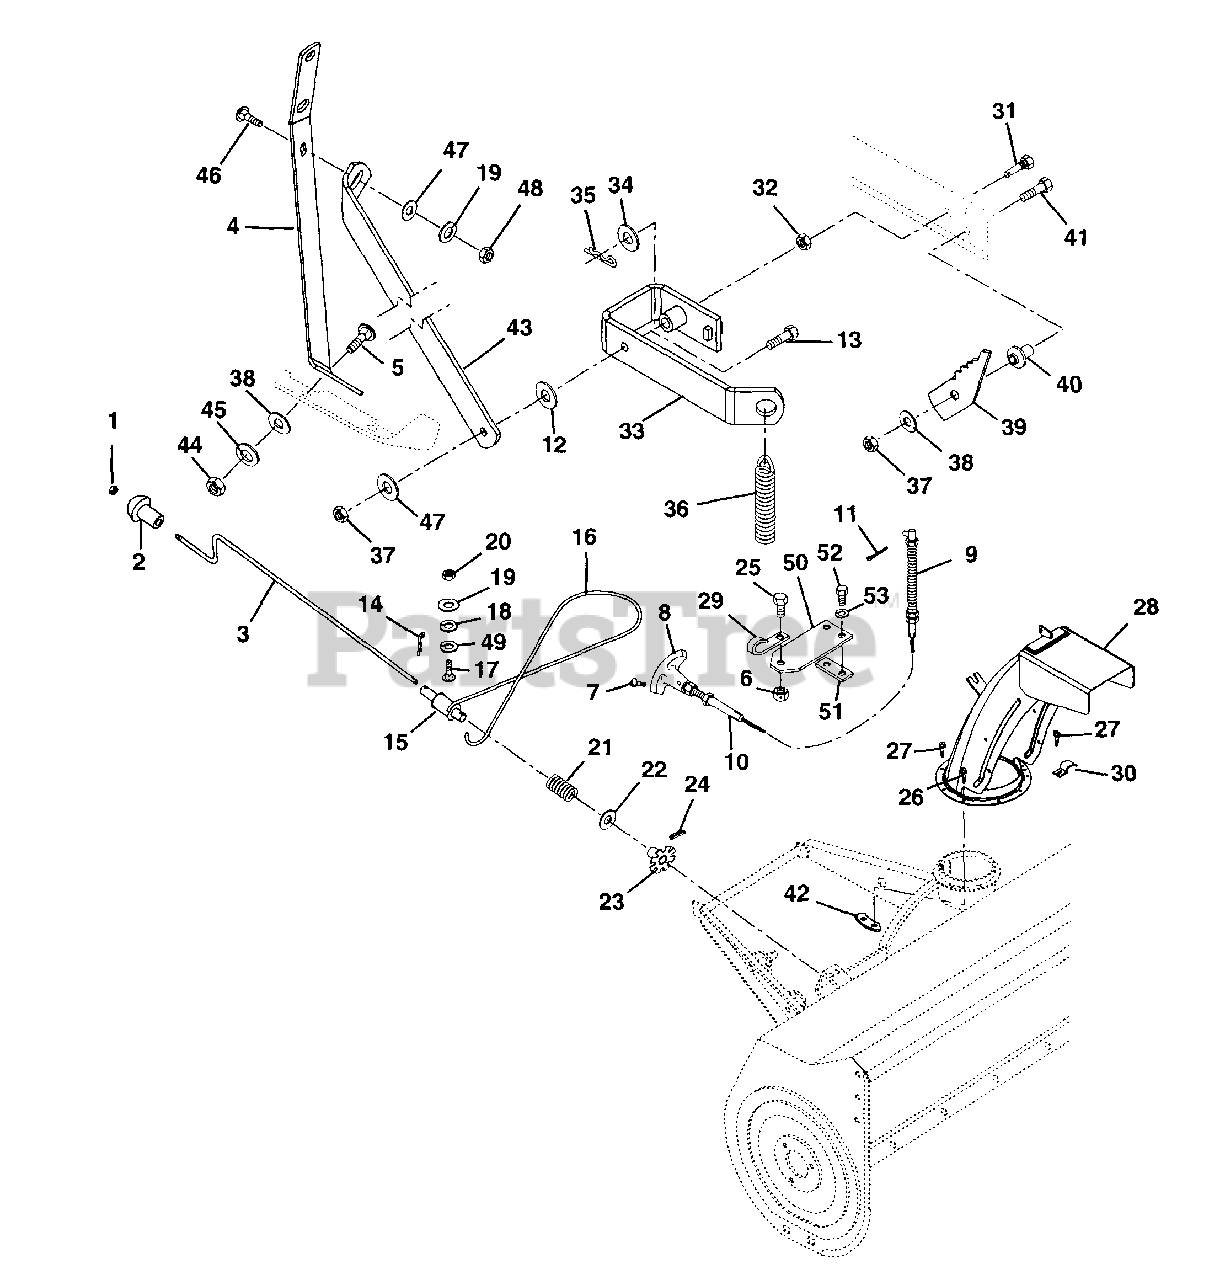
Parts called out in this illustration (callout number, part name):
1	@NUT-LK-CTR-JAM .375-16 YWZC
3	CHUTE CONTROL CRANK
4	SUPPORT, ROD
5	@BLT-RDHDSQNK .38-16X1.00 G5YZ
6	@NUT-LK-CTR .38-16 YWZC
7	@SCR-MCH 8-32X.75 HWH YWZC
8	KNOB, CONTROL
10	CABLE, CONTROL W/HANDLE/SCREW
11	@PIN-CTR .09X.75 EXTPRSQCT YWZ
12	@WSHR-FL-STL.38X.875X.083 YWZC
13	@BLT-HEX .31-18X1.00 GR5 YWZC
14	PIN-HAIR INT .08X.38X1.42 YWZC
15	SPOOL
17	@BLT-RDHDSQNK .25-20X.75 G5YZ
18	@WSHR-FL-STL.281X.62X.065 YWZC
19	@WSHR-LK-EXT.262X.502X.026YWZC
20	@NUT-HEX .25-20 YWZC
21	SG-COMP .054X.75X1.6
22	@WSHR-FL-STL.656X1.31X.095 YWZ
23	DISC ASSEMBLY
24	PIN-ROLL .188X1.00
25	@BLT-HEX .38-16X.50 GR5 YWZC
26	SCR-TAP 12-24X.50 TORX YWZC TR
27	SCR-TAP 12-24X.75 TORX PL TR
28	CHUTE, DISCHARGE W/CAP-KRKL BL
29	J-CLAMP
30	CABLE CLAMP
31	STUD-WEIGHT
32	@NUT-LK-CTR .50-13 YWZC
33	SPRING ARM
34	NUT-HEX-JAM .375-16 YWZC
35	PIN-HAIR INT .08X.18X1.18 YWZC
36	SG-TENS .188X1.50X8.5 WLD 57
37	@NUT-LK-CTR .31-18 YWZC
38	@WSHR-FL-STL.38X.875X.083 YWZC
39	SPRING ASSIST CONTROL
40	SPACER .323X.498X.531X1.000
41	@BLT-HEX .31-18X1.25 GR5 YWZC
42	CHUTE CLAMP
44	@NUT-HEX .38-16 YWZC
45	@WSHR-LK .38X.094 REG YWZC
46	@BLT-RDHDSQNK .31-18X1.00 G5YZ
47	@WSHR-FL-STL.344X.688X.065YWZC
48	@NUT-HEX .31-18 YWZC
49	WSHR-LK PYM .31X.062YWZC
50	BRACKET, CABLE HOLDER
51	PLATE, CABLE HOLDER
52	@BLT-HEX .25-20X.50 GR5 YWZC
53	@WSHR-LK .25X.062 REG YWZC
